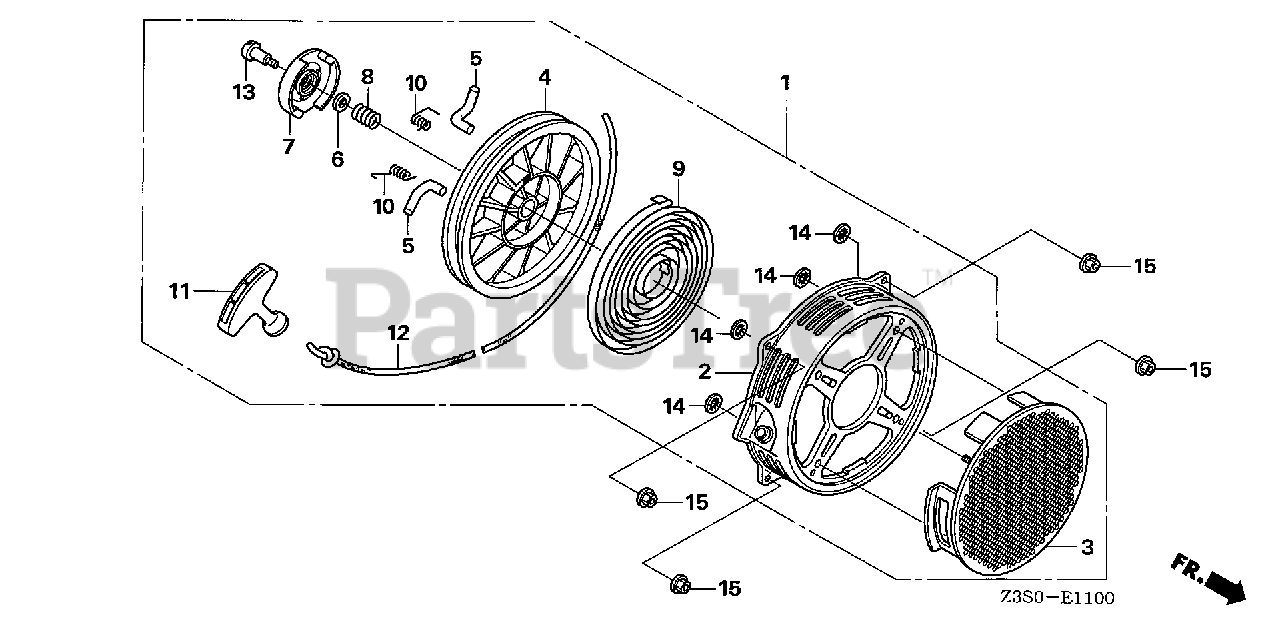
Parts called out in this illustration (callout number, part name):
1	STARTER ASSY., RECOIL *R280* (POWER RED)
2	CASE, RECOIL STARTER *R280* (POWER RED)
3	COVER, RECOIL STARTER
4	REEL, RECOIL STARTER
5	RATCHET, STARTER
6	PLATE, FRICTION
7	GUIDE, RATCHET
8	SPRING, FRICTION
9	SPRING, RECOIL STARTER
10	SPRING, RETURN
11	GRIP, STARTER
12	ROPE, RECOIL STARTER
13	SCREW, SETTING
15	NUT, FLANGE (6MM)
